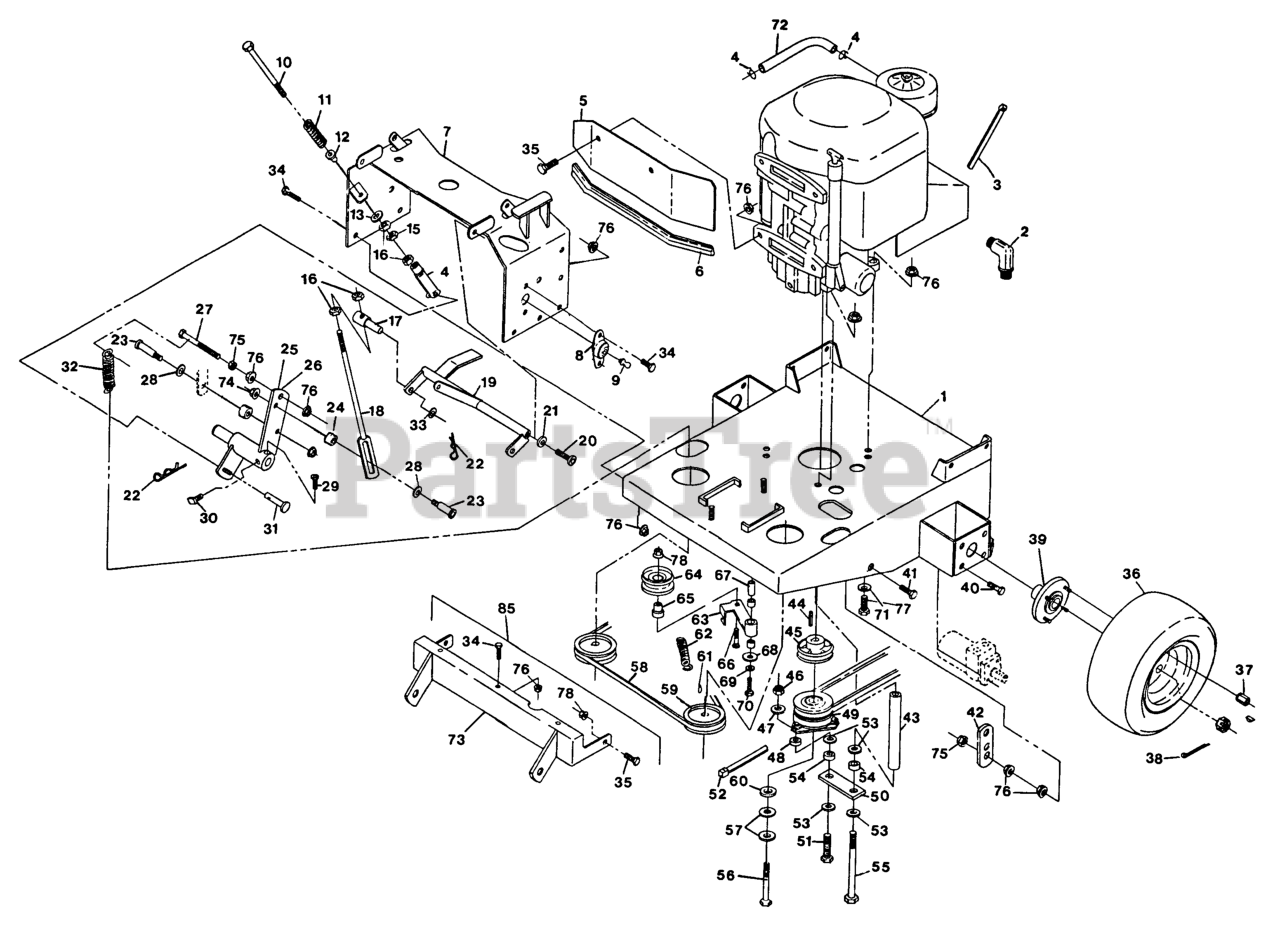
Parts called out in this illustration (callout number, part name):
2	FITTING-ELBOW-90
3	TIE-CABLE
5	SHIELD-HEAT, TRACER
8	FLANGE MTG, SIDE
10	BOLT-RETURN, NEUTRAL
11	SPRING-RETURN, NEUTRAL
12	BUSHING-FLANGED
14	YOKE-ADJUSTABLE
20	SCREW-HSH
22	PIN-COTTER
23	SCREW-HSH
26	WLD,LH CONTROL ARM
30	SCREW-SET
31	PIN-CLEVIS
32	SPRING-EXTENSION
38	PIN-COTTER
41	BOLT-TAP, HH
42	ANCHOR-SPRING
52	TIE-PLASTIC
54	SPACER,CLUTCH ANCHOR
55	SCREW-HH
57	WASHER-SPRING
58	BELT-HYDRO TRANS DR
59	SHEAVE - PUMP
60	BUSHING,CLUTCH KEEPER
62	SPRING-EXTENSION
63	IDLER ARM ASM
65	BUSHING-IDLER
67	BUSHING
71	WASHER-SPRING
72	HOSE-FUEL
73	WLD,SULKY HITCH
79	Engine - 14 Hp Kawasaki
83	BELT,DECK DRIVE
84	SLEEVE-BEARING
85	Turf Tracer Hydro Kit, Hitch Sulky
